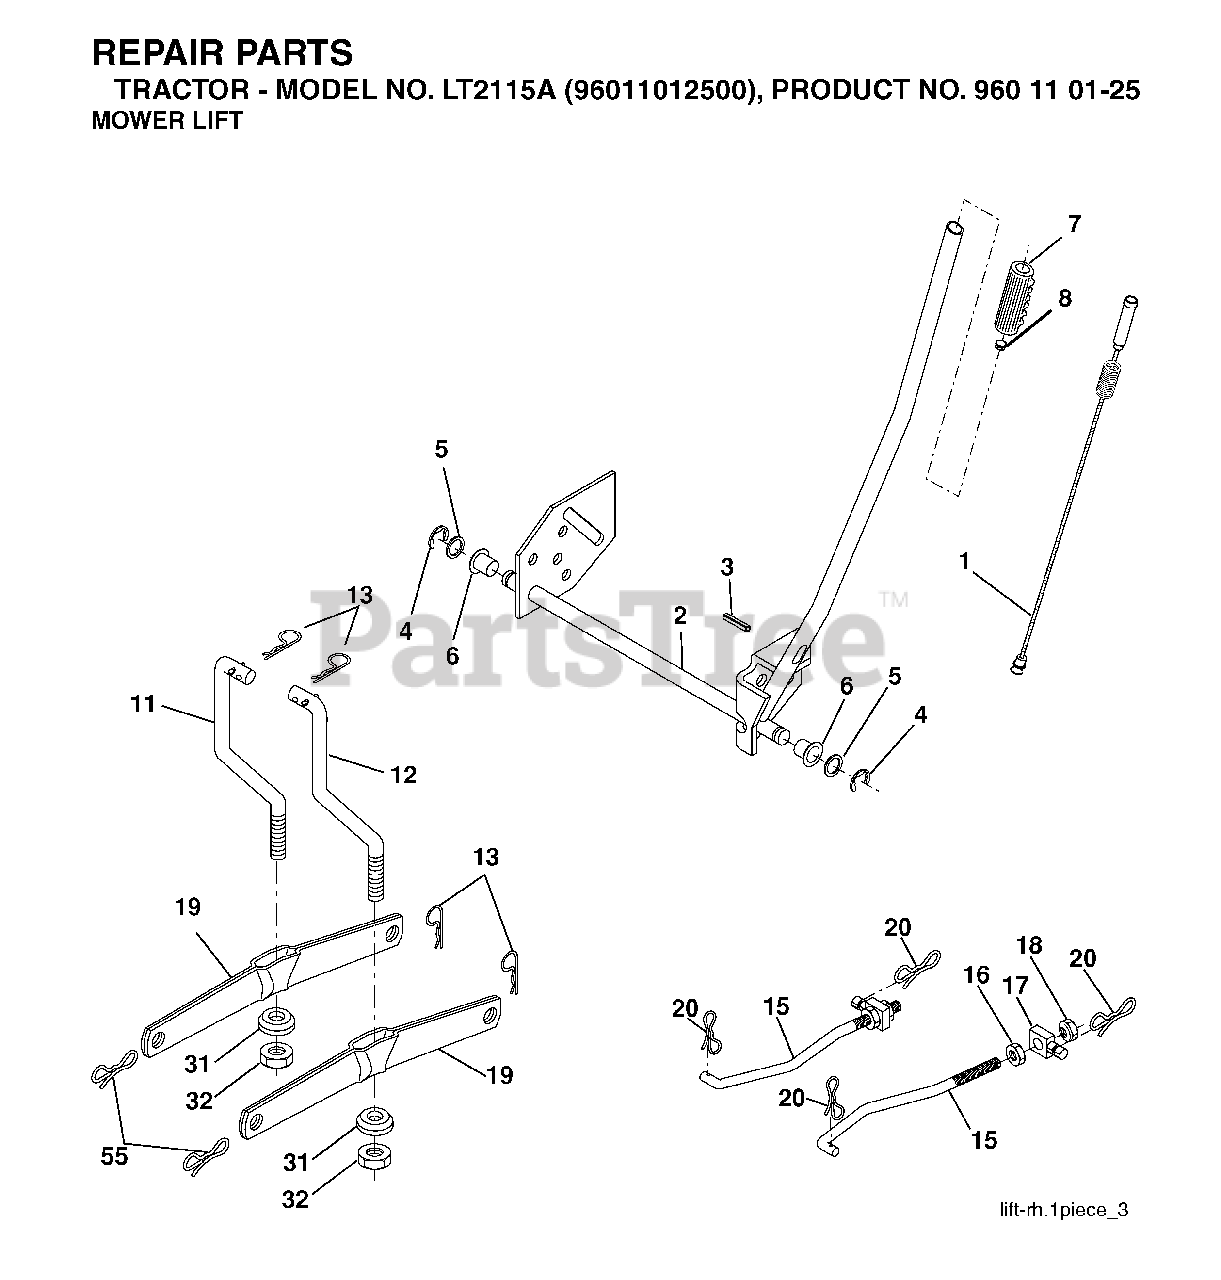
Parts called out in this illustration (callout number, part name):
4	RETAINING RING LT
6	BEARING.NYLON
7	GRIP
11	LINK LIFT LH
12	LINK LIFT RH
13	RETAINER-SPRNG RB
15	LINK.SUSPENSION.FRONT
16	NUT
18	NUT
19	ARM.REAR.SUSPENSION
20	PIN.COTTER.7/16.BOW TI
31	BEARING.PIVOT.LIFT
32	NUT CROWNLOCK 3/8-24
50	PIN.COTTER.5/16.BOW TI
